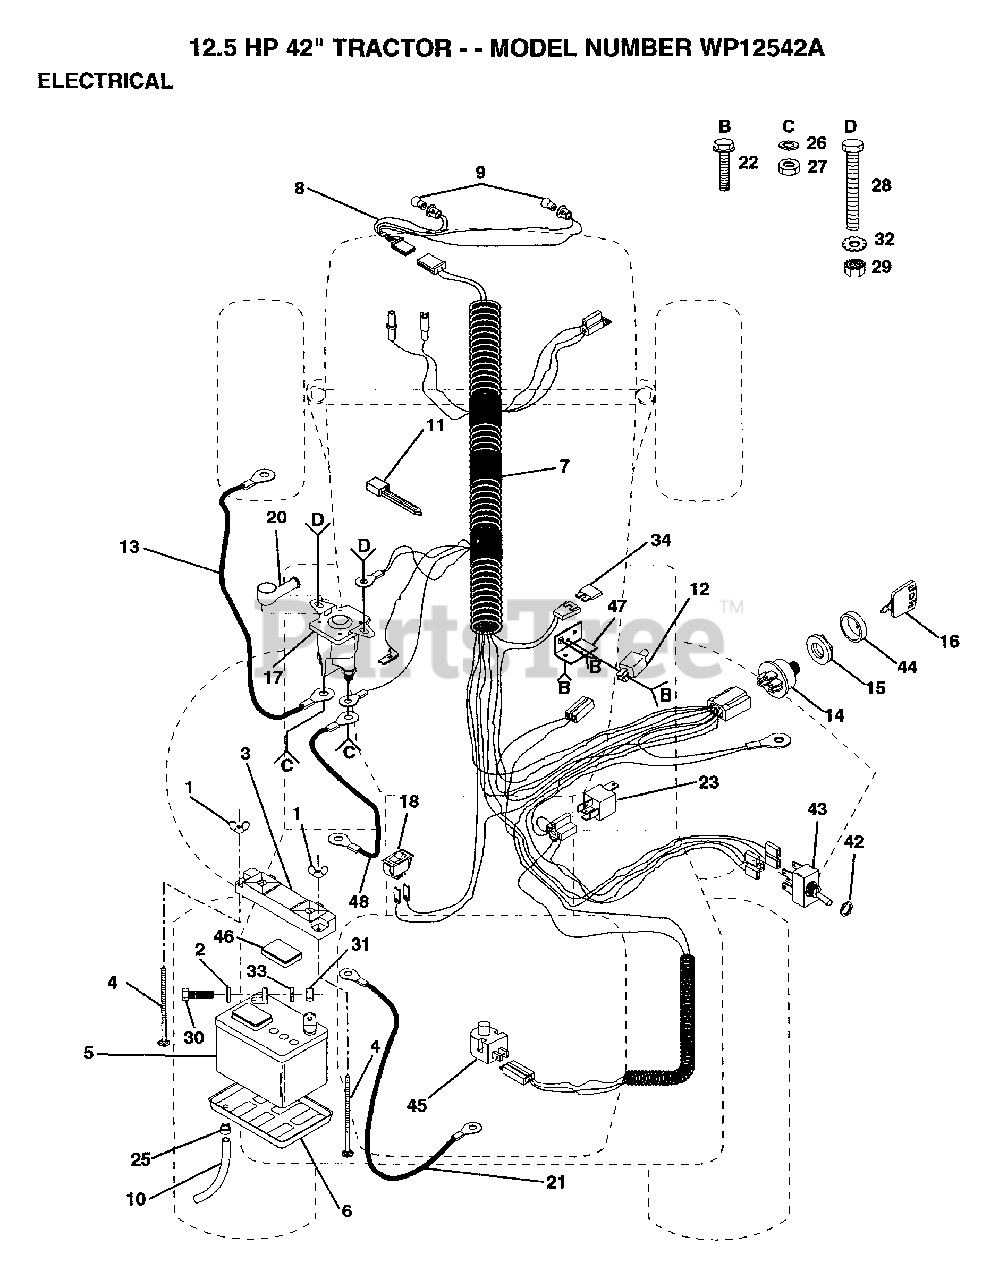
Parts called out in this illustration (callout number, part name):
2	WASHER
4	BOLT
6	"TRAY T, BATTERY"
7	"HARNESS,IGNITION"
11	WIRE TIE
12	SWITCH INTERLOCKT
13	"CABLE T, BATTERY"
15	NUT IGNITION
16	KEY
21	CABLE T
22	SCREW
23	RELAY ASSY T
25	HOSE CLAMP T
27	NUT
28	BOLT
29	NUT
30	BOLT LT
33	LOCKWASHER
34	FUSE HYT
42	HEX NUT T
46	"CAP,BATTERY "
47	BRACKET LT
48	CABLE-BATTERY T
